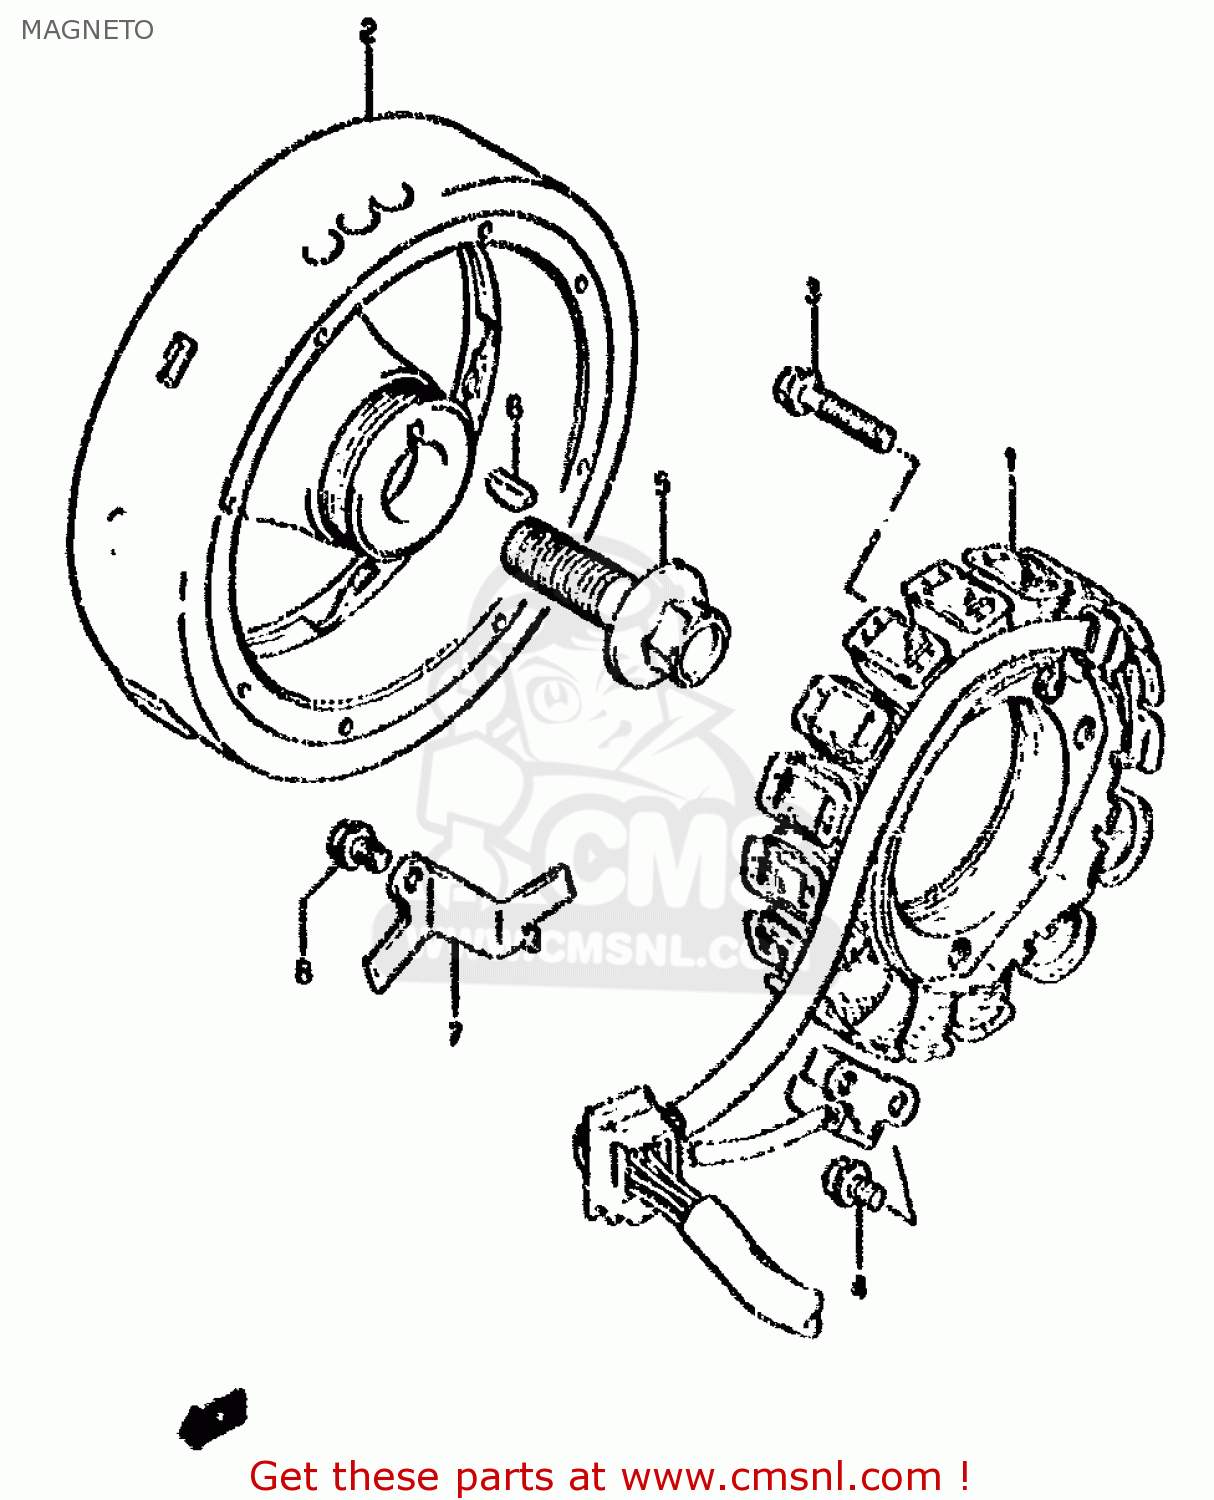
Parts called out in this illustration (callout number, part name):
1	STARTER ASSY
2	ROTOR
3	BOLT
4	BOLT
5	BOLT(14X43)
6	KEY
7	CLAMP,MAGNETO LEAD WIRE
8	BOLT
